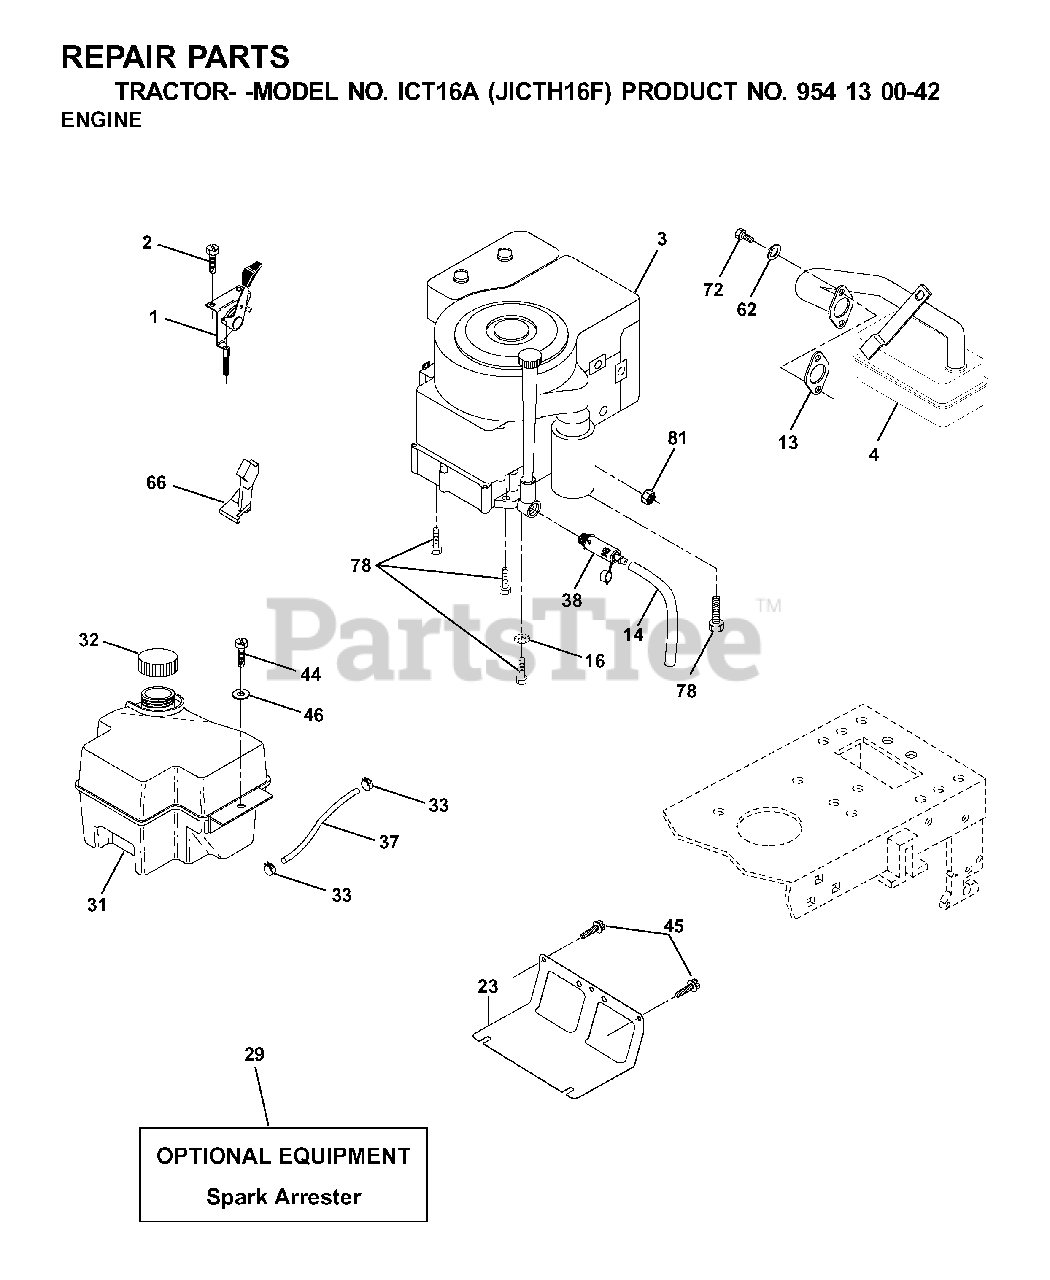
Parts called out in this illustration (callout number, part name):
1	THROTTLE CONTROL CABLE
2	SCREW LT
13	REPL BY 532 27 22-93
14	TUBE, DRAIN OIL ASM.
16	LOCKWASHER
23	SHEILD.BROWNING.DBR.GUARD
29	ARRESTER SPARK (OPTIONAL)
31	FUEL TANK
32	FUEL CAP
33	HOSE CLAMP
37	LINE.FUEL.20
38	PLUG, OIL DRAIN EASY
44	SCREW HEXWSHR 1/4-20X3/4
45	SCREW, 3/8-16X3/4
62	LOCKWASHER
66	STOP THROTTLE
72	SCREW
78	SCREW.3/8-16
81	NUT
